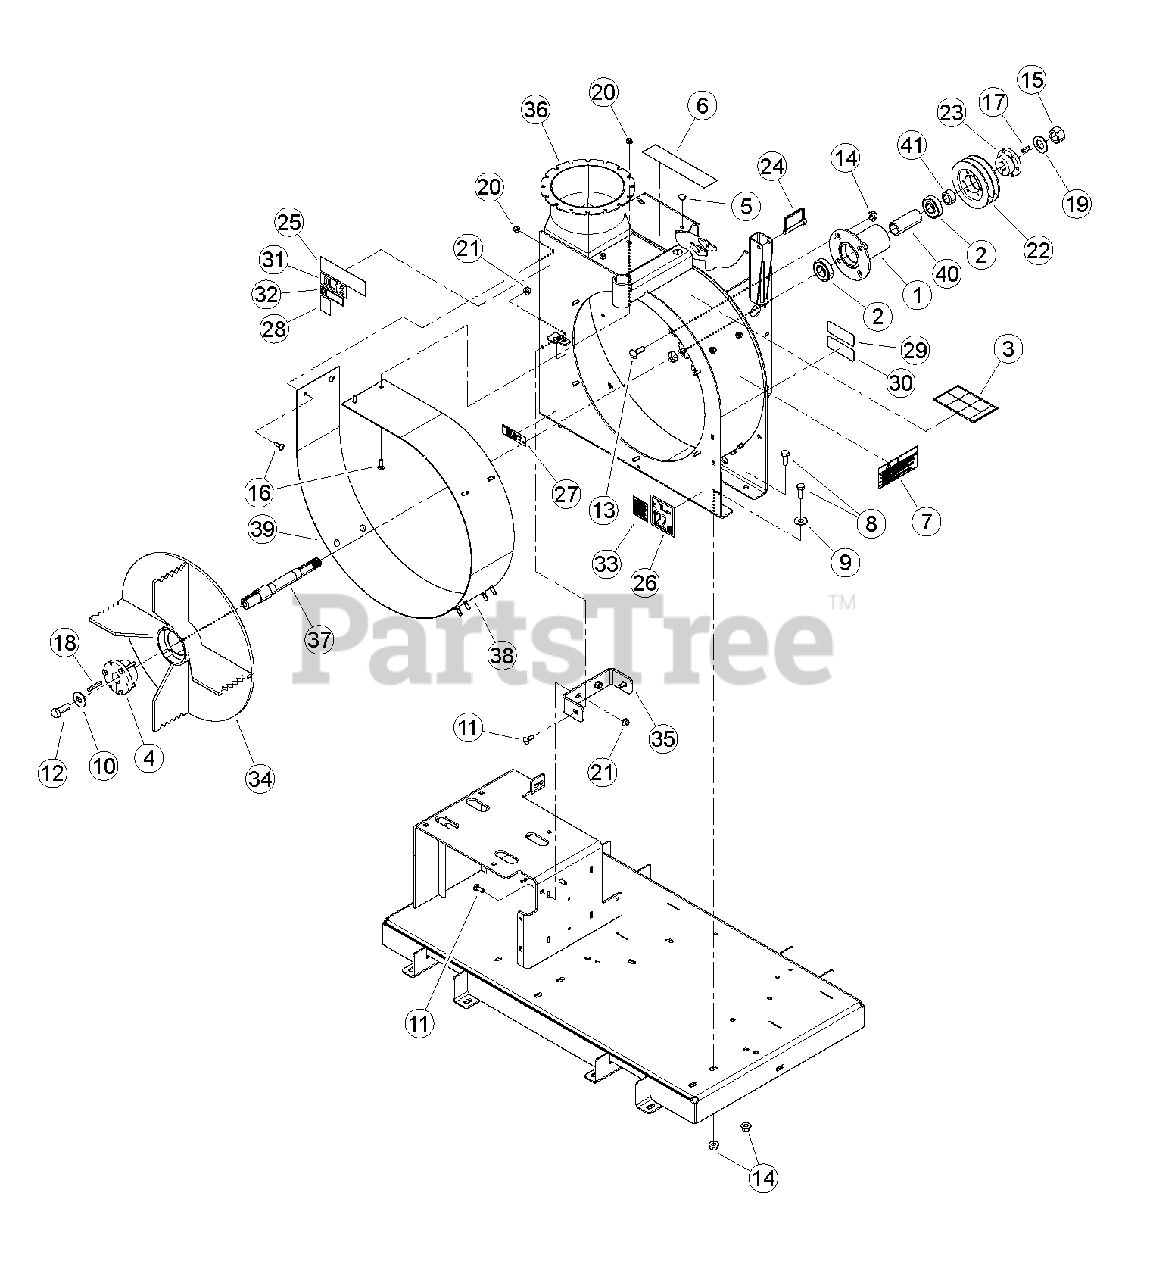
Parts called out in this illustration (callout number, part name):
1	BEARING, HUB (MACHINED)
2	BEARING, 30MM
3	DECAL, OPERATING INSTRUCTIONS ISO
4	BUSHING, SK 1-1/4"
5	BUMPER, RUBBER
6	DECAL, ROTOR ENGAGEMENT
7	DECAL, MUTILINGUAL MANUAL
8	BOLT, 1/2 X 1-1/4" GR5 HHCS NC ZP
9	WASHER, 1/2 FLAT
10	WASHER, 5/8" FLAT ZP
11	BOLT, 3/8-16 X 1 GR5 CRG
12	BOLT, 5/8 X 1-3/4 G5 NF HEX CAP ZP
13	BOLT, 1/2" X 1-1/2" GR5 CRG ZP
14	NUT, 1/2-13 NYLOCK FLANGE
15	NUT, 1" CENTERLOCK NC ZP
16	BOLT, 5/16-18 X 1 GR5 CRG
17	KEY, 1/4" SQ X 1" LG
18	KEY, 1/4" SQ X 2" PLAIN
19	WASHER, 1" SAE FLAT ZP
20	NUT, 5/16-18 NYLOCK-FLANGE
21	NUT, 3/8-16 NYLOCK FLANGE
22	SHEAVE, 2B5.2 SDS
23	BUSHING, SDS 1"
24	PIN, 3/8 X 2-1/2 LYNCH
25	DECAL, ECHO BEARCAT 6.82 X 1.90
26	DECAL, 122 DB
27	DECAL, ATLANTIC BRIDGE LTD INFO
28	DECAL, ECHO BEARCAT QR CODE
29	DECAL, EPA EVAP
30	DECAL, CARB EVAP
31	DECAL, MODEL DL12
32	DECAL, DL12 INFORMATION
33	DECAL, SPARK ARRESTOR
34	WELDMENT, FAN "BEAR CLAW"
35	PLATE, SUPPORT
36	WELDMENT, FAN HOUSING
37	SHAFT, VACUUM FAN
38	WRAP, HOUSING FAN
39	WRAP, HOUSING FAN
40	SPACER, BEARING HUB
41	SPACER, 1-1/2 X 11/16
